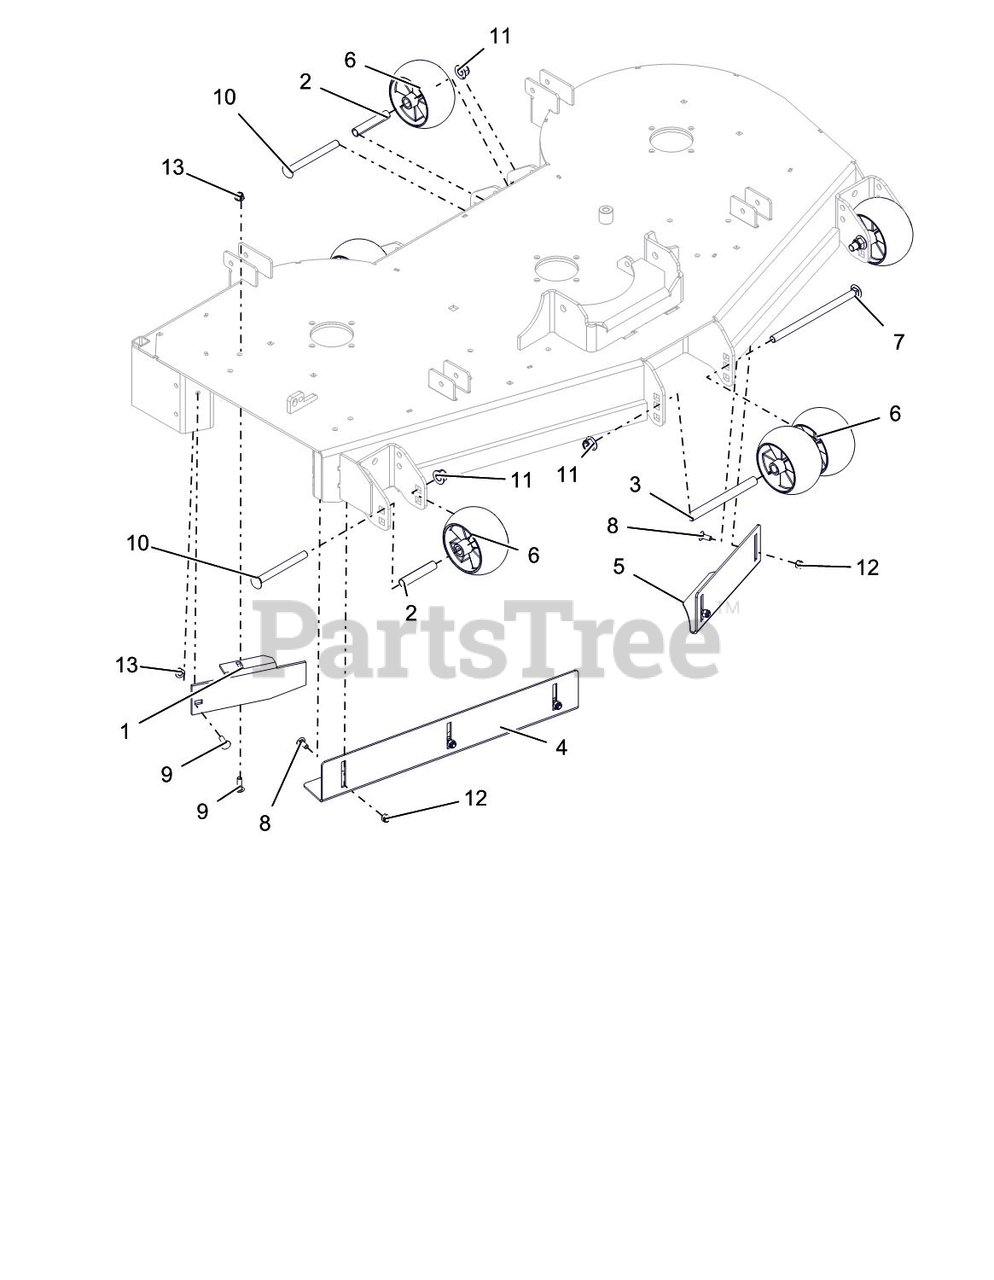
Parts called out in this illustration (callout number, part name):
1	BAFFLE, 52" DISCHARGE-RED
2	SPACER, .510X.625X3.35-BLACK
3	SPACER, .510 X .625 X 6.50
4	BAFFLE, 52" RH VACUUM-BLACK
5	BAFFLE, 52" LH VACUUM-BLACK
6	ANTI-SCALP WHEEL - 5X3 CTR
7	BLT-RDHDSQNK .50-13X8.50 Y
8	BLT-RDHDSQNK .31-18X.75 G5 YWZC
9	BLT-RDHDSQSHNK .31-18X1.00 G5 Y
10	BLT-RDHDSQNK .50-13X5.00 G5 YWZC
11	NUT-LK-NYL-FLG .50-13 YWZC
12	NUT-LK-NYL .312-18 YWZC
13	NUT-LK-NYL-FLG .31-18 YWZC
